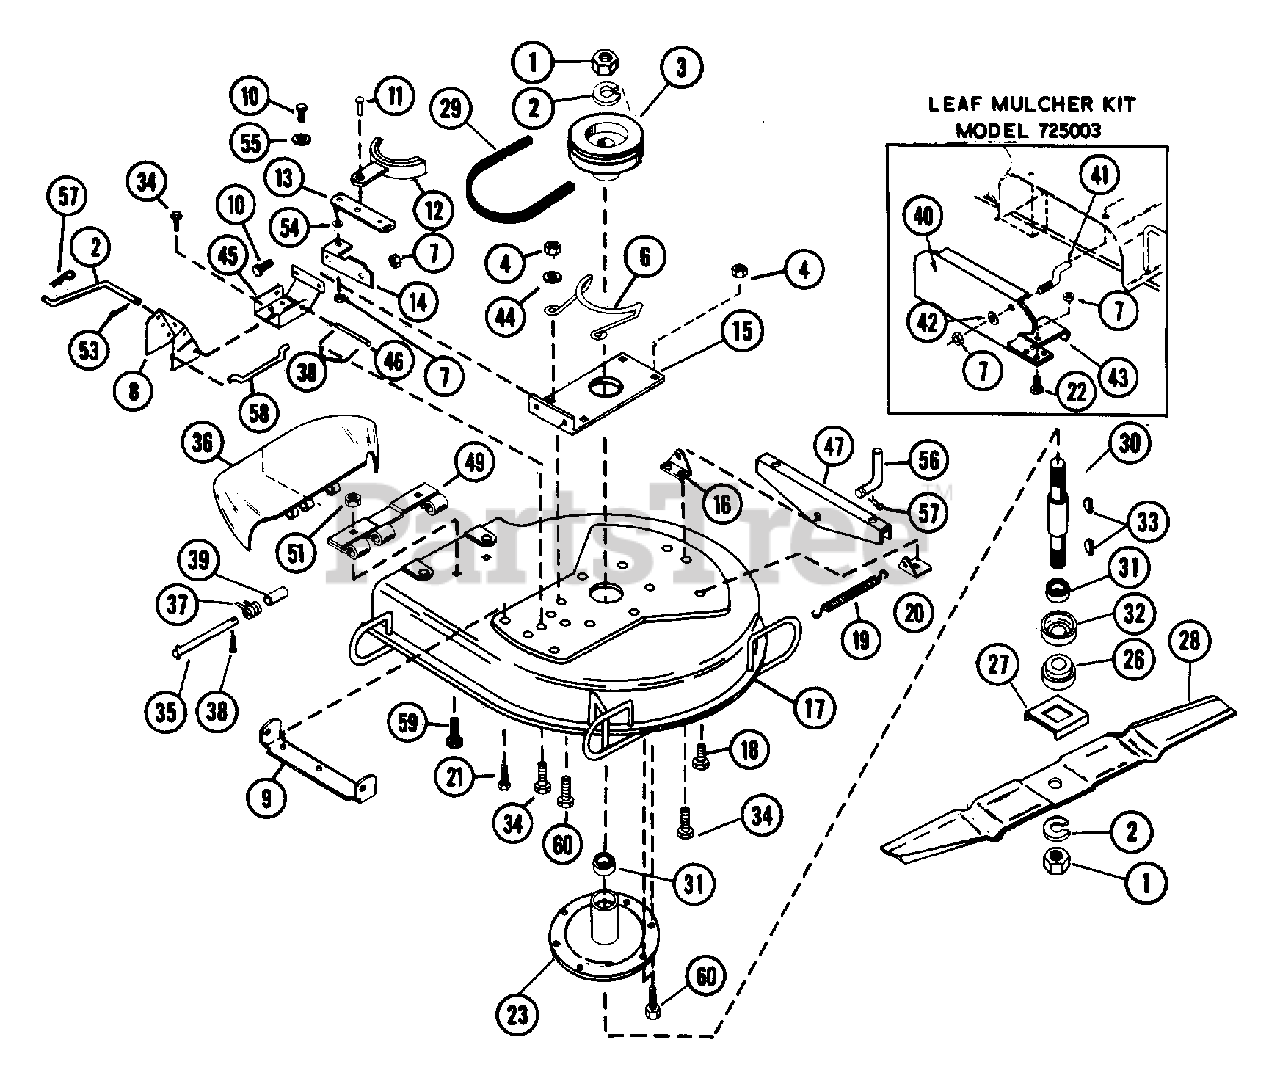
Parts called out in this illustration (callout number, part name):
1	NUT-JAM .75-10 PL
2	WSHR-LK .750X.188 MED PL
3	MOWER SHEAVE
4	NUT-LK-CTR .375-16 GR A PL
6	BELT FINGER
7	NUT-LK .312-18 GR A PL
8	MOWER ENGAGING ARM
9	FRONT MTG BRACKET
10	BLT-HEX .31-18X.63 PL GR 2
11	RVT .25X.50 RH ST
12	BLADE BRAKE
13	MOWER BRAKE LEVER
14	BRAKE BRACKET
16	REAR MTG BRACKET
17	26 IN MOWER PAN W/ DECALS
18	BLT-SERHFWH .25-20X.50 PL
19	SG-TENS .072X.51X5.31 WLD 25
20	BRAKE CLIP
21	BLT-SCRHFWH .38-16X.50 PL
22	BLT-HEX .31-18X.50 PL GR2
23	SPINDLE HOUSING
26	RETAINER HUB
27	BLADE TRAY
28	MOWER BLADE 26
29	V-BELT, 4L-WRAPPED
30	SPINDLE SHAFT
31	BRG-BALL .750X1.781X.61
32	BEARING SLINGER
33	KEY-WDRF .188X.75X.313 SAE 9
34	BLT-SERHFWH .31-18X.50 PL
35	CLEVIS PIN
36	PAN CHUTE EXTENSION
37	SG-TORS .095X.50X 1.0
38	PIN-COTR .09X.75 PL
39	BSHG-SLV .334 X .502 X 1.437
40	LEAF MULCHER KIT-EMPEROR
42	WSHR-FL-STL .38X.875X.083 PL
43	MULCHER BRACKET
44	WSHR-FL-STL .406X.865X.094 PL
45	PIVOT BRACKET
46	PIN-CLEV .309X3.50 SP
47	SWIVEL BRACKET
49	HINGE PLATE
51	NUT-LK-CTR .250-20 PL
52	MOWER ENGAGEMENT LINK
53	PIN-COTR .12X.75 PL
54	SPACER
55	WSHR-FL-STL .328X1.0X.094
56	CLEVIS PIN
57	PIN-HAIR INT .08X.38X1.42 YWZC
58	MOWER BRAKE LINK
59	BLT-RDHDSQNK .25-20X.50 SHT PL
60	BLT-HEX .38-16X1.00 PL
